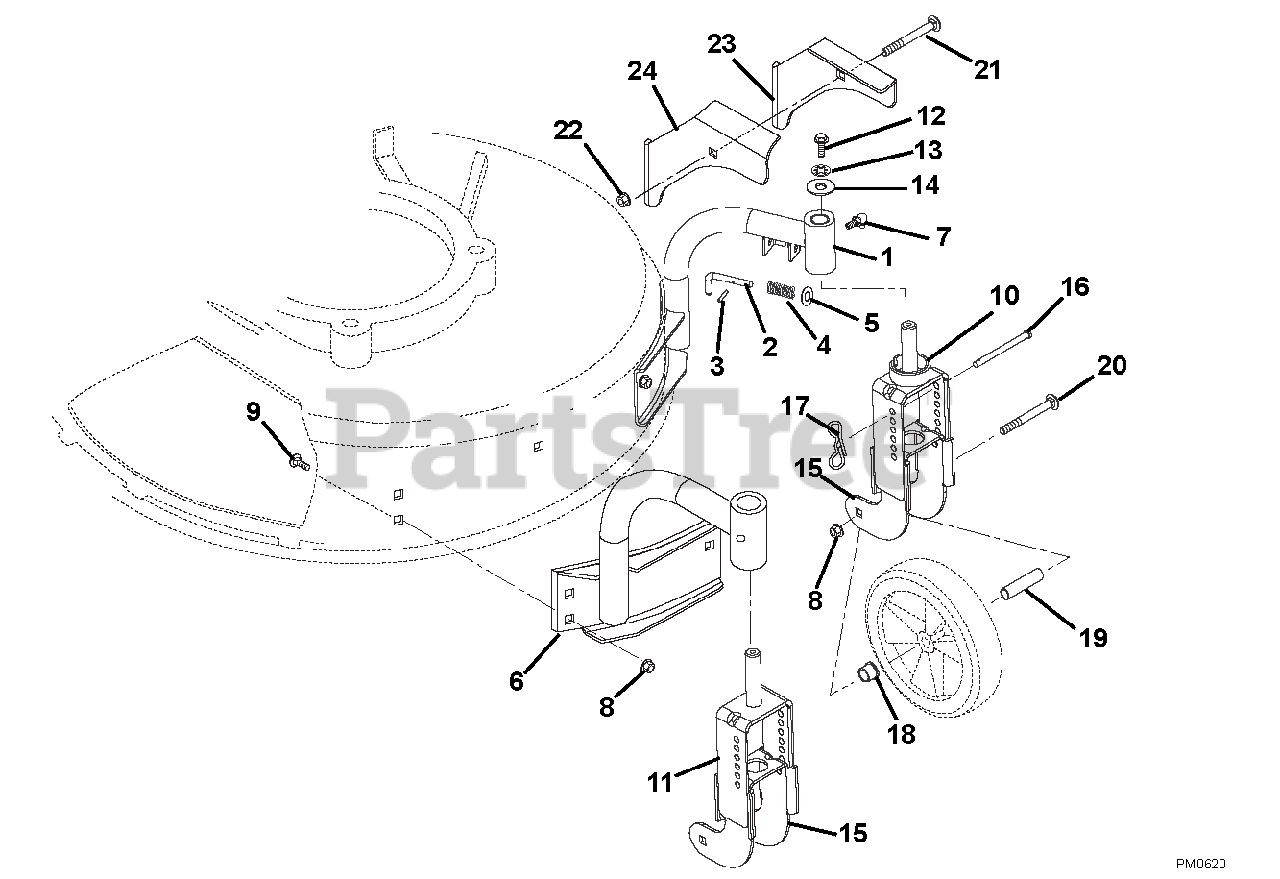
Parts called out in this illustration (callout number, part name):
1	ASSY, MOUNT LH W/BUSHINGS
2	PIN, LOCKOUT
3	PIN-ROLL .093X.50
4	SPRG, COMP--SWVL LOCKOUT
5	@WSHR-FL-STL.281X.62X.065 YWZC
6	ASSY, RH MOUNT W/BUSHINGS
7	FTG-LUBE .25-28X.256 YWZC
8	@NUT-SPNLK-FLG .312-18 YWZC
9	@BLT-RDHDSQNK .31-18X.50 G5YZ
10	YOKE, OUTER LH
11	YOKE, RH OUTER
12	@BLT-HEX .25-20X.75 GR5 YWZC
13	@WSHR-LK .25X.062 REG YWZC
14	WSHR-FL-STL .281X1.000X.063
15	YOKE-INNER
16	PIN, HEIGHT ADJUSTMENT
17	PIN, BOW TIE LOCKING COTTER
18	BSHG-FLG .500X.625X.500X.750
19	SPCR, WHEEL .385X.500X2.00
20	BLT-RDHDSQSHNK.31-18X2.75G2YWZ
21	@BLT-RDHDSQNK .25-20X1.50 G5YZ
22	@NUT-SPNLK-FLG .25-20 YWZC
23	BRACKET, HOOD CABLE--LH
24	BRACKET, HOOD CABLE WELDMENT
